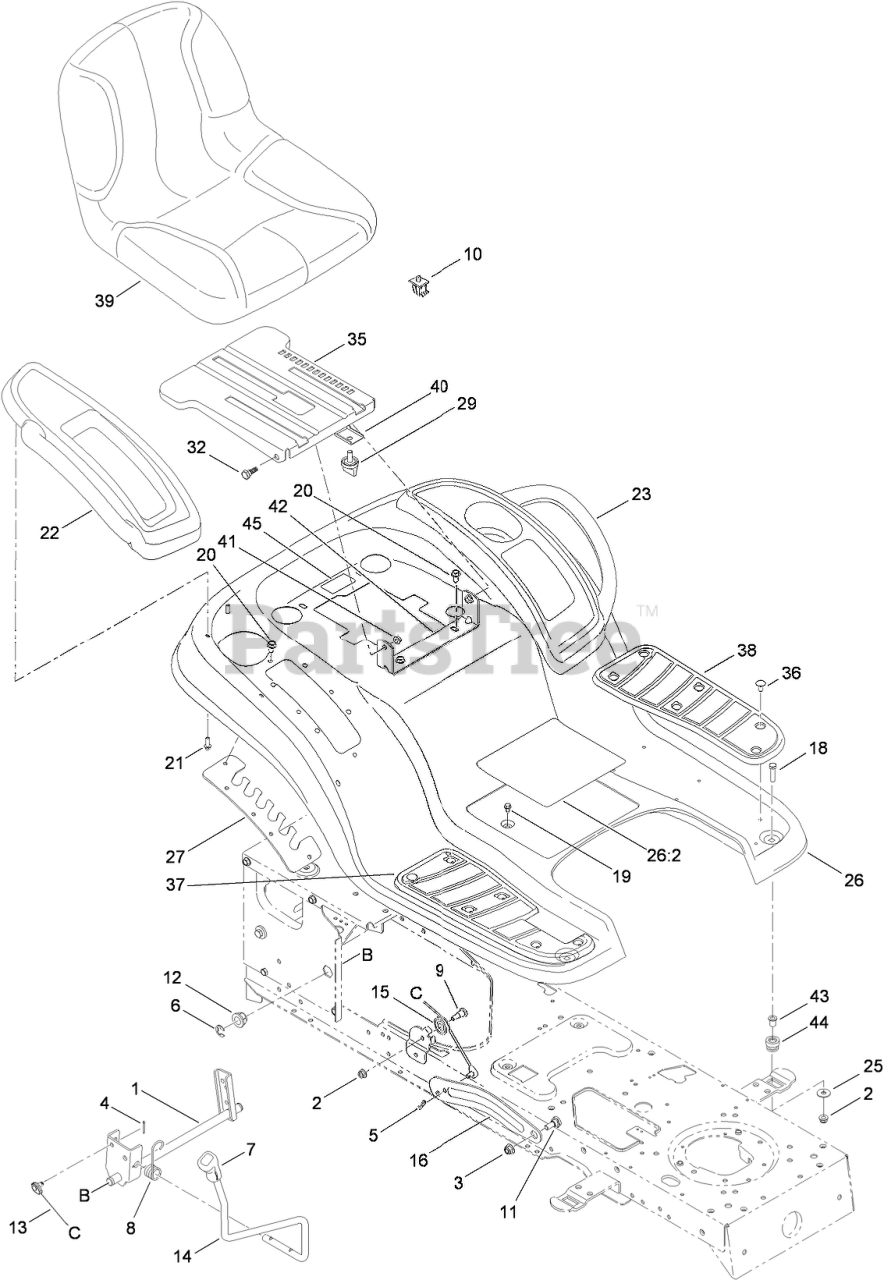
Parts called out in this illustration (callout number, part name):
1	LIFT SHAFT ASM
2	NUT-LOCK, FLANGE
3	NUT-LOCK, FLANGE
4	PIN-COTTER
5	PIN-COTTER
6	RING-E
7	GRIP-HANDLE
8	SPRING-TORSION
9	BOLT-SHOULDER
10	Switch-Seat
11	BOLT-SHOULDER
12	BEARING-FLANGE
13	CABLE-LIFT
14	HANDLE-LIFT
15	PULLEY-ROLLER
16	ARM-LIFT, RH
18	SCREW-HH
19	SCREW-HWHTF
20	SCREW-TAP
21	SCREW-TAP
22	COVER-FENDER, RH
23	COVER-FENDER, LH (W/CUPHOLDER)
25	WASHER-FLAT
26	FENDER WITH DECAL
26:2	DECAL-SAFETY
27	BRACKET-ADJUSTING, LIFT
32	BOLT-SHOULDER
35	BRACKET-MOUNT, SEAT
36	CLIP-RATCHET, FASTENER
37	PAD-FOOT, RH
38	PAD-FOOT, LH
39	SEAT-HIGH
40	BRACKET-KNOB, ADJUSTMENT
41	NUT-LOCK, FLANGE
42	BRACKET-PIVOT, SEAT
43	SPACER
44	GROMMET
45	DECAL-TORO HOTLINE
